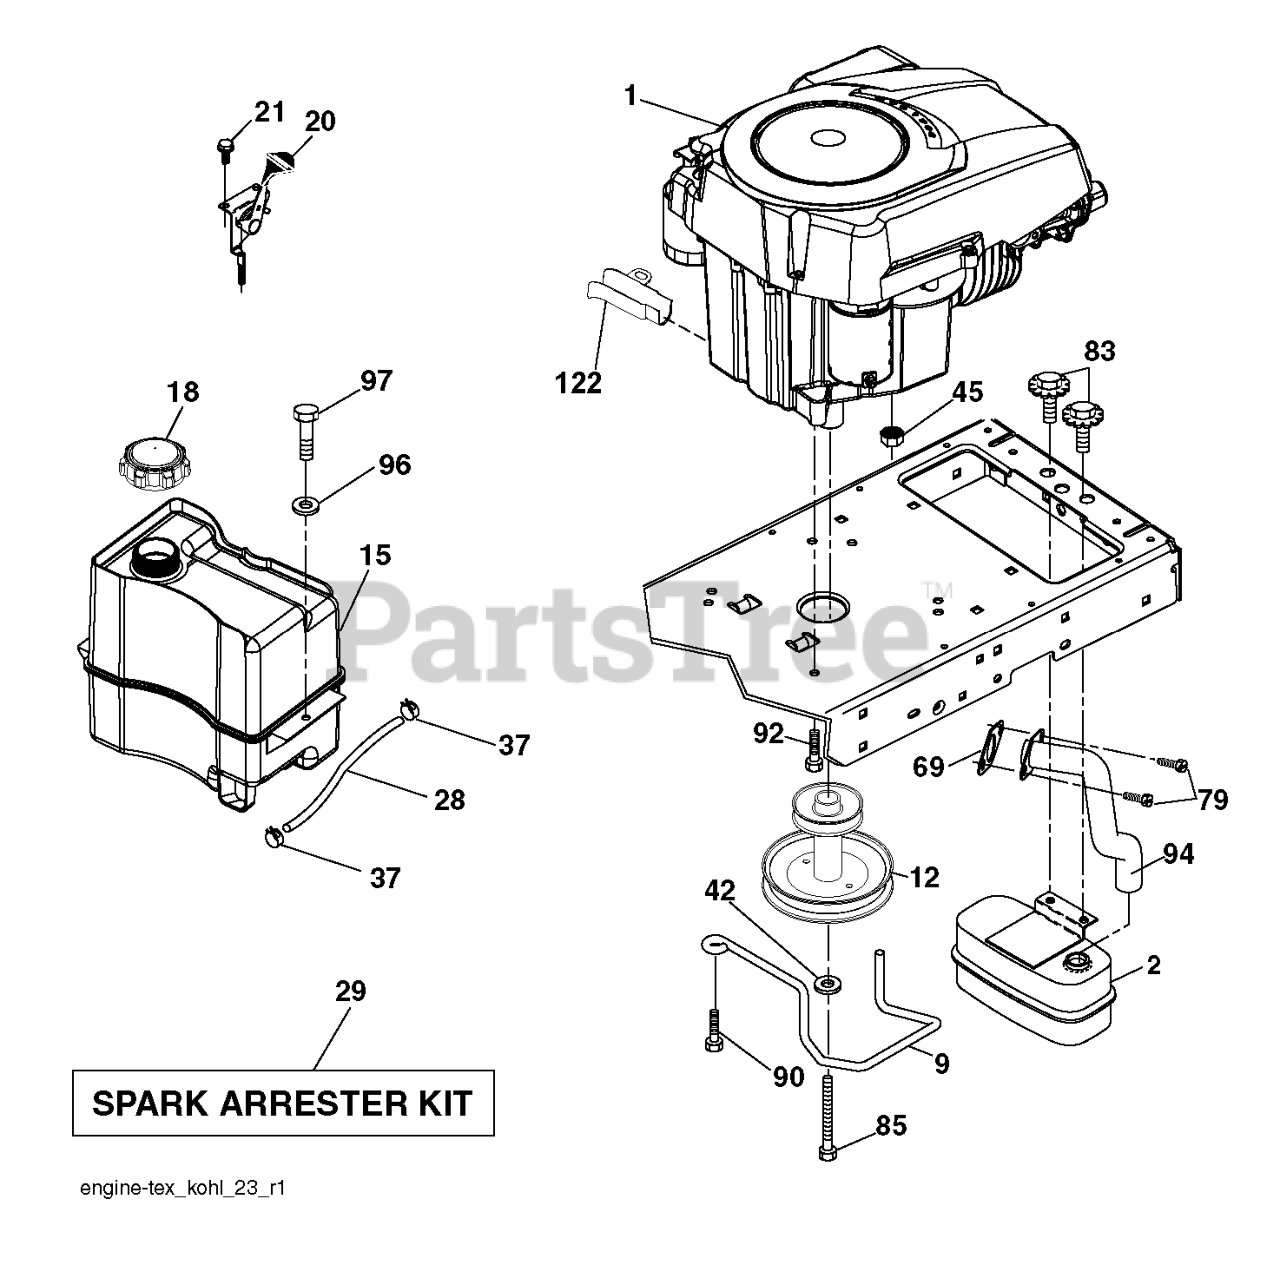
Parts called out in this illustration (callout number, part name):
2	MUFFLER.SINGLE.CYL.KOHL/B&S
9	KEEPER.BELT.ENGINE.3.25 (3 2)
12	PULLEY ENGINE
15	RP TANK FUEL FRT 1.5 GAL
18	CAP.FUEL.2.25"VENTED"
20	CONTROL.TH/CK.C.
21	SCREW.#10 X 0.750.BOS
28	LINE.FUEL.20
29	KIT.SPARK ARRESTOR 794945 B&S
37	HOSE CLAMP
42	LOCKWASHER
45	NUT
69	GASKET.EXHAUST.KOHLER
79	SCREW.SOCKET HD.5/16-1
83	BOLT.5/16-18UNCX3/4 W/SEMS.BLK
85	BOLT HEX 7/16-20X4-1/4"
90	SCREW 3/8-16X1
92	SCREW 3/8-16X1
94	RP.TUBE.EXHAUST.KOHL.COURAGE
97	SCREW HEXWSHR 1/4-20X3/4
122	EXTENSION DRAIN OIL
